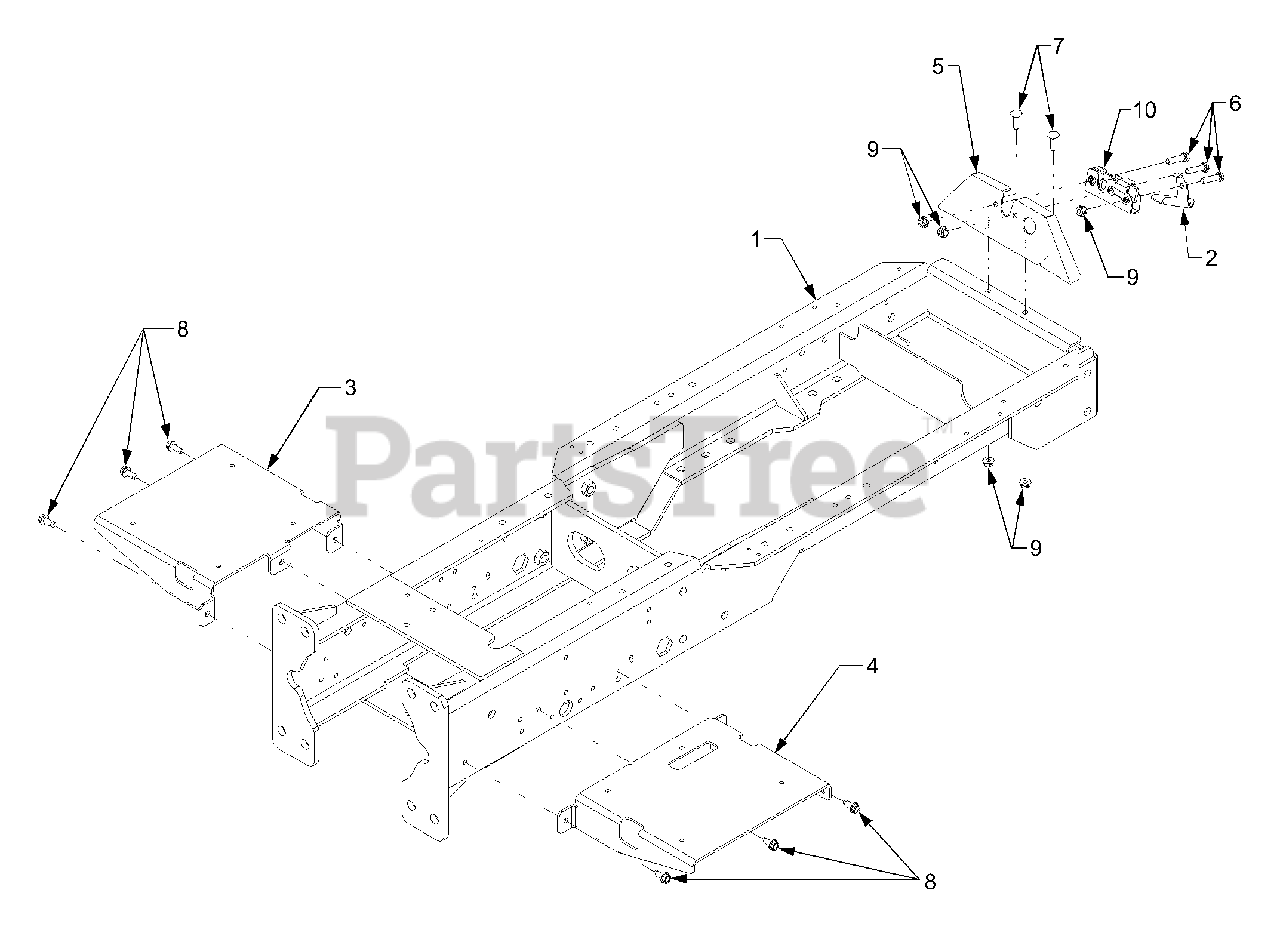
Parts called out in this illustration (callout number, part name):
1	Frame
2	Lever, Hood Latch
3	Bracket, Running Board Mtg. LH
4	Bracket, Running Board Mtg. RH
5	Bracket, Hood Latch Mtg.
6	Screw, Hex Cap, 5/16-18 x 1.375 GR5
7	Screw, Carriage, 5/16-18 x .75
8	Screw, Hex Wash. Hd. 5/16-18 x .75
9	Nut, Hex Flange Lock, 5/16-18
10	Latch, Hood
